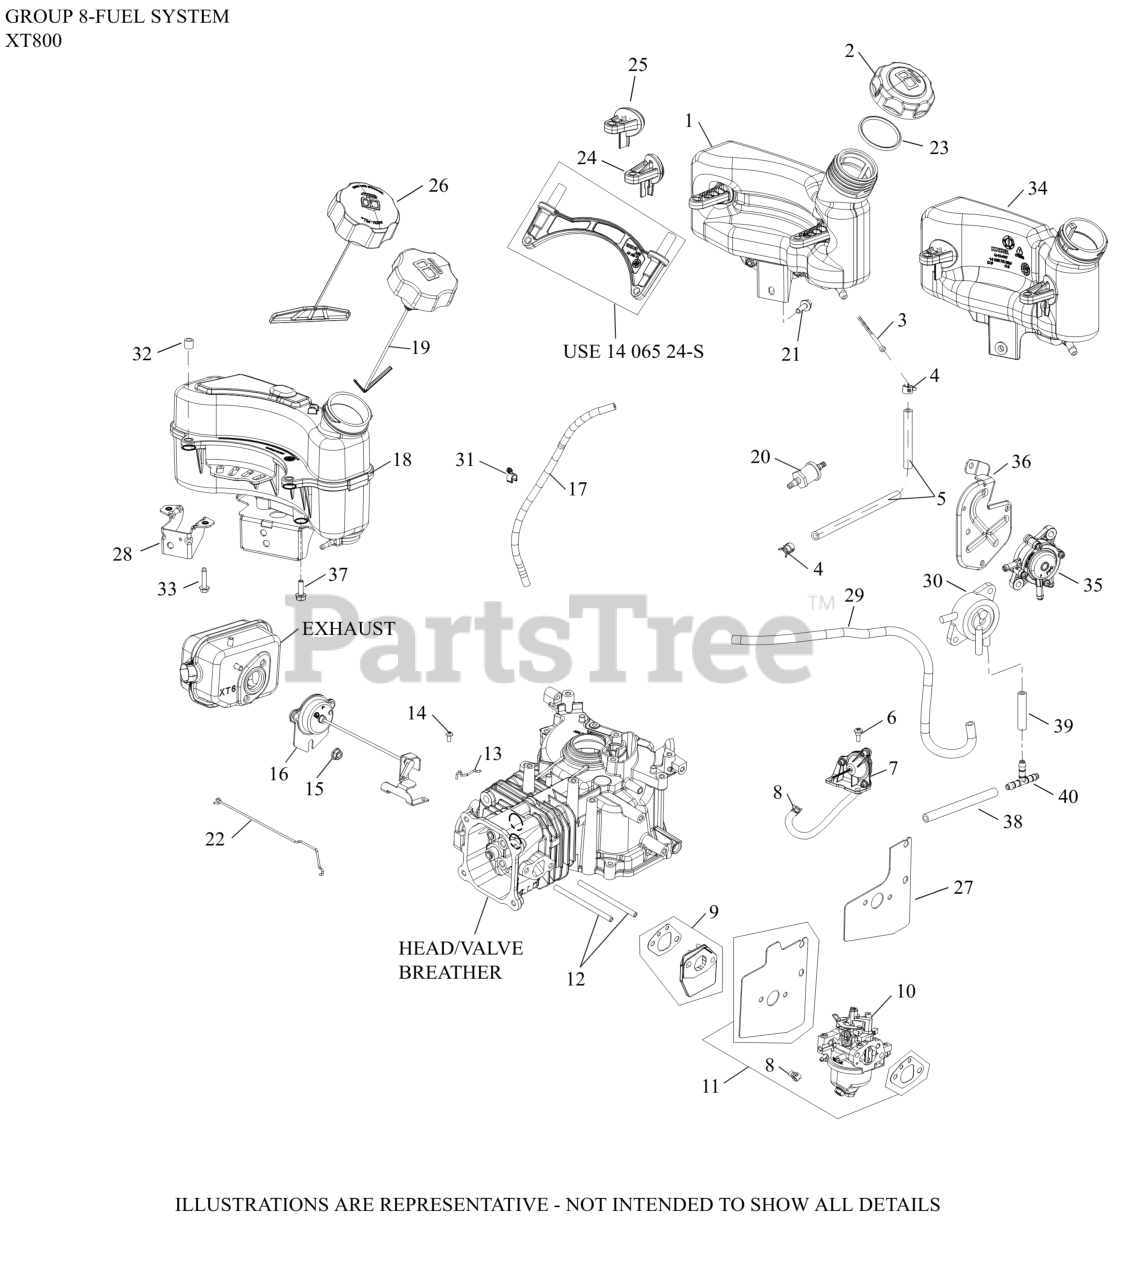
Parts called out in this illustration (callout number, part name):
3	FILTER, FUEL IN-NIPPLE
4	CLAMP, HOSE (NON-CALIF)(#1423710S)
5	HOSE, FUEL LOW-PERMEATION
6	SCREW, SHOULDER-(#25086440S)
7	DIAPHRAGM, ASSEMBLY
8	CLAMP, HOSE
9	KIT, SPACER
10	KIT, CARBURETOR 13 MM AUTO CHOKE
11	KIT, CARBURETOR HEAT SHIELD GASKET
12	STUD,M6X1.0X100.2MM
13	LINKAGE, AUTO CHOKE
14	SCREW, M4 THRD FRMNG-(#25086439S)
16	ARM ASSY, AUTO CHOKE-USE 14 187 19-S
17	HOSE, EVAPORATIVE
18	TANK, FUEL 1.4L FOR EUROPE ONLY
19	CAP ASSEMBLY, FUEL
21	SCREW, HEX FLANGE (M6)
23	SEAL, FUEL CAP
NI	KIT, HIGH ALTITUDE - USE 14 755 04-S
NI	KIT, CARBURETOR REPAIR (RUIXING)
